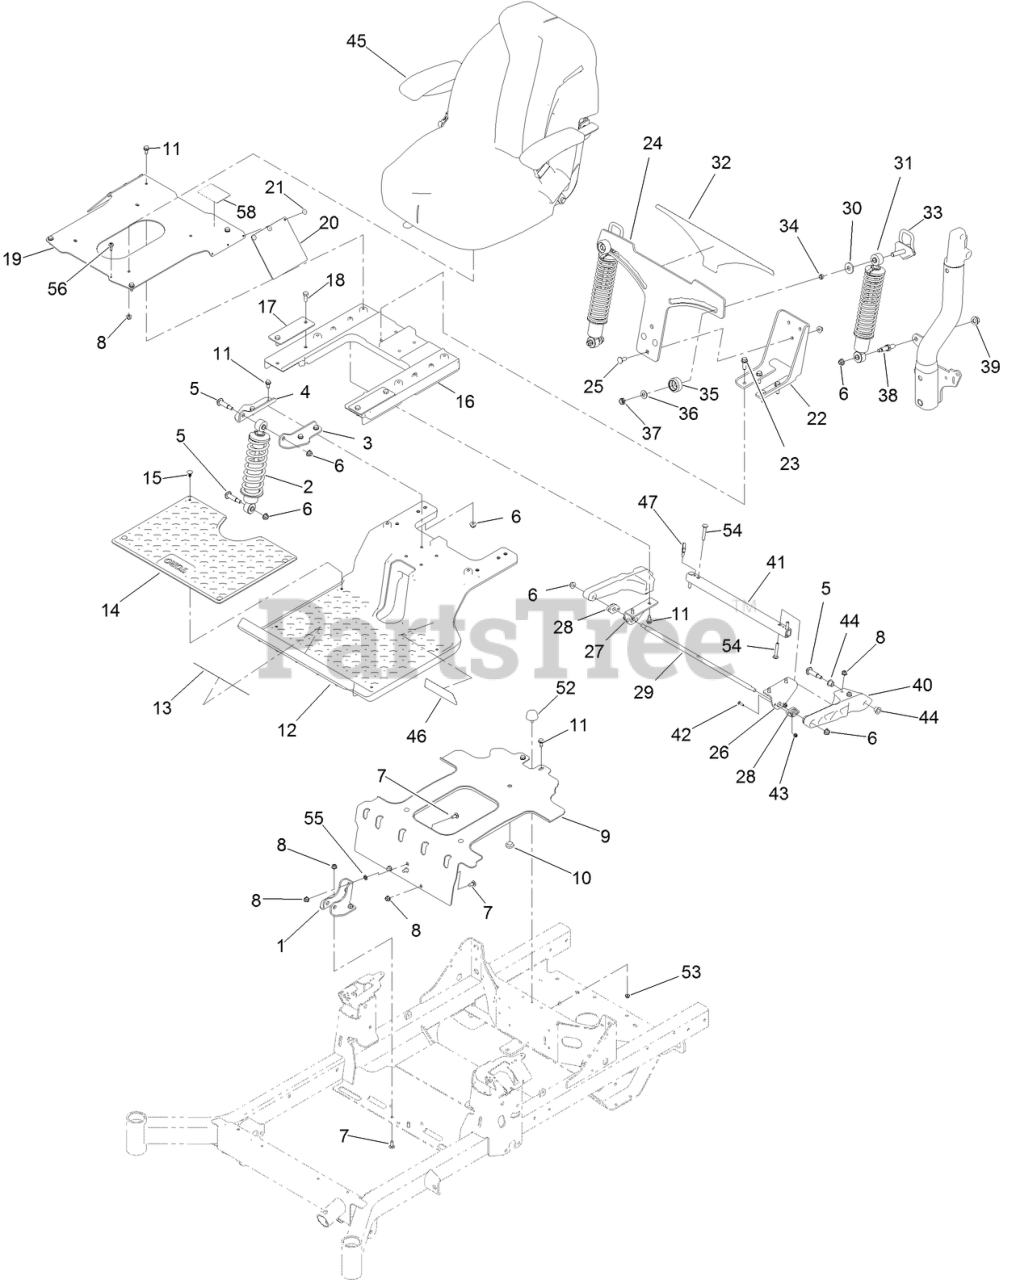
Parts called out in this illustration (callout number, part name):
1	BRACKET-SHOCK, FRONT LOWER
2	SHOCK/SPRING
3	BRACKET-SHOCK MOUNT, UPPER (LH)
4	BRACKET-SHOCK MOUNT, UPPER (RH)
5	BOLT-SHOULDER, HWH
6	NUT-HF, NI
7	SCREW-CARR
8	NUT-HF, NI
9	BRACKET-TANK
10	BUMPER-SEAT
11	SCREW-HWHTF
12	SUBFRAME-FRONT
13	DECAL-DANGER
14	FLOORMAT
15	PLUG-PLASTIC
16	SUBFRAME-REAR
17	PLATE-BACKER
18	SCREW-HH
19	PLATE-SEAT
20	FLAP-RUBBER
21	RIVET-POP
22	BRACKET-MOUNT, LOWER
23	SCREW-THD
24	PLATE-MOUNTING, ADJ SHOCK
25	SCREW-CARR
26	BRACKET-ARM, TRAILING (LH)
27	BRACKET-ARM, TRAILING (RH)
28	BEARING-FLANGE
29	ROD-PIVOT
30	WASHER-PLASTIC
31	SHOCK/SPRING ASM
32	DECAL-MYRIDE
33	CAM LOCK ASM
34	BEARING-SLEEVE
35	KNOB-LOCK, CAM
36	WASHER-ADJUSTING
37	NUT-HEX
38	BOLT-SHOULDER
39	NUT-LOCK
40	TRAILING ARM
41	TUBE-ARM, TRAILING
42	SCREW-CARR
43	NUT-HF
44	BUSHING-FLANGE
45	SEAT ASM
47	CLAMP-HOSE
52	BUMPER
53	NUT-HF
54	BOLT-CARR
55	NUT-PUSH
56	SCREW-SHOULDER
58	DECAL-AID, SERVICE
